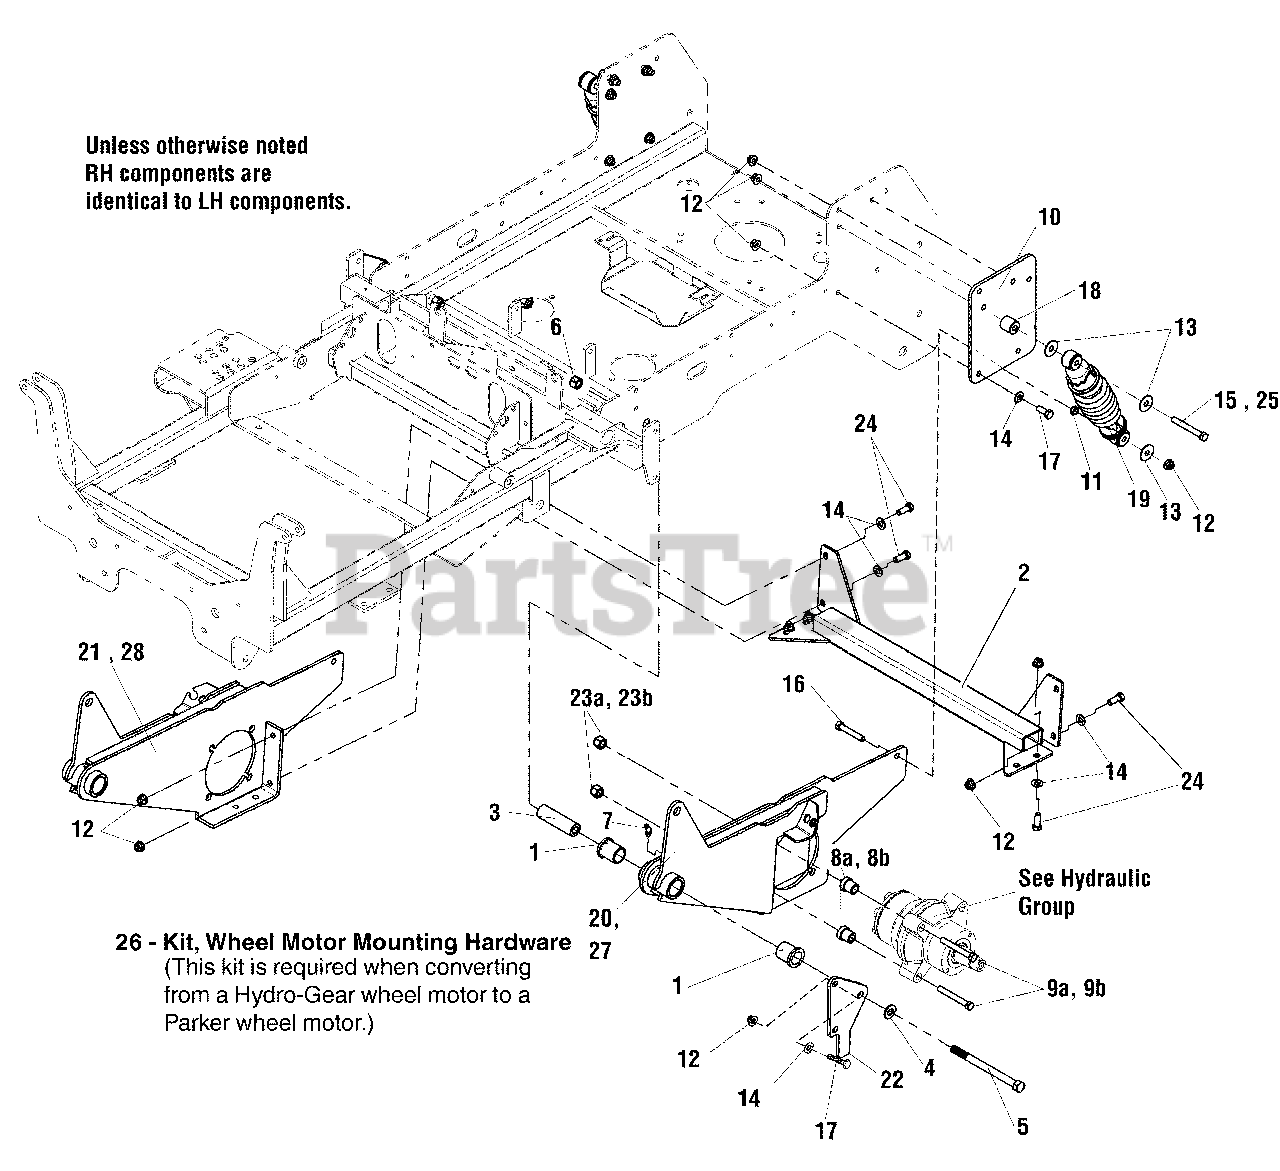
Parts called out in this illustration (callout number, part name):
1	BUSHING, FLANGE
2	KIT, TIE BAR, 61 (5404051A)
3	SPACER, .52 X 1.00 X 3.42
4	WASHER, 1/2" SAE
5	BOLT, 1/2-13 X 6-1/2" GD5
6	NUT, 1/2-13 HEX NYLON LOCK
7	GREASE FITTING, 1/4-28 STRAIGHT
10	PLATE, FRAME SUPPORT
11	SPACER, .39 X 1.00 X .50
12	NUT, 3/8-16 HEX NYLOCK FLANGE
13	WASHER, 3/8" FENDER
14	WASHER 3/8" SAE
15	BOLT, 3/8-16 X 3-1/2" GD5 YZ
16	BOLT, 3/8-16 X 2-1/4" GD5 YZ
17	BOLT, 3/8-16 X 1" GD5
18	SPACER, .39 X 1.00 X 1.25, CZ
19	COIL - OVER SHOCK ASSEMBLY
20	WELD, MOTOR MOUNT, LH - ORANGE
21	WELD, MOTOR MOUNT, RH - ORANGE
22	SUPPORT, SWING ARM - BLK
24	BOLT, 3/8-16 X 1-1/4 GD5
25	BOLT, 3/8-16 X 3-1/2" GD5 YZ
26	* KIT, WHEEL MOTOR MOUNTING HARDWARE
27	WELD, MOTOR MOUNT, LH - ORG
28	WELD, MOTOR MOUNT, RH - ORG
